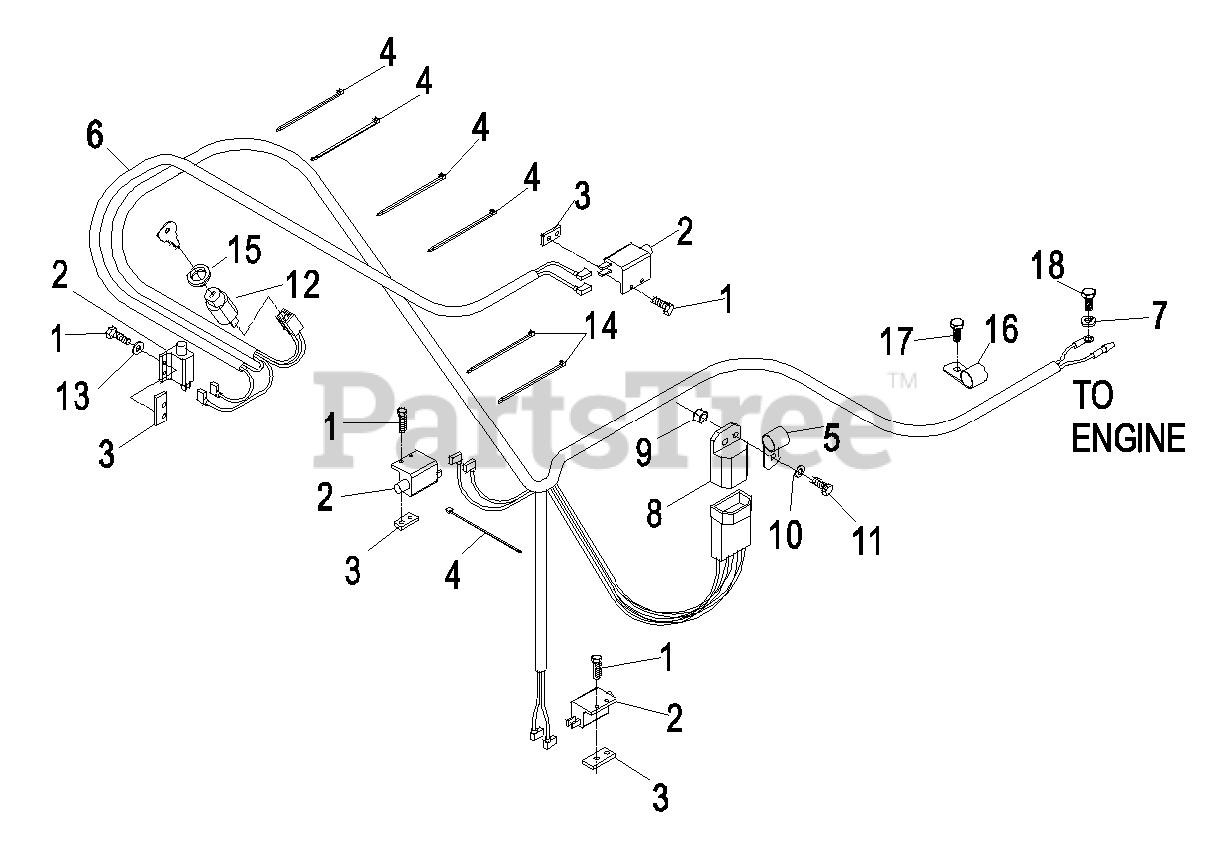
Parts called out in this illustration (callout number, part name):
1	SCREW-PPH
2	SWITCH-OPEN, NORMALLY
3	PLATE-TAPPED
4	TIE-CABLE
5	CLIP-LOOM
6	HARNESS,WIRING KA PULL ST
7	WASHER-LOCK
8	MODULE-INTERLOCK
9	NUT-LOCK, NI
10	WASHER-FLAT
11	SCREW-HH
12	SWITCH & KEY (INCLUDES NU
13	WASHER-FLAT
14	TIE-PLASTIC
15	NUT-SWITCH, IGNITION
16	CLIP-LOOM
17	SCREW-HH
18	SCREW-HH
